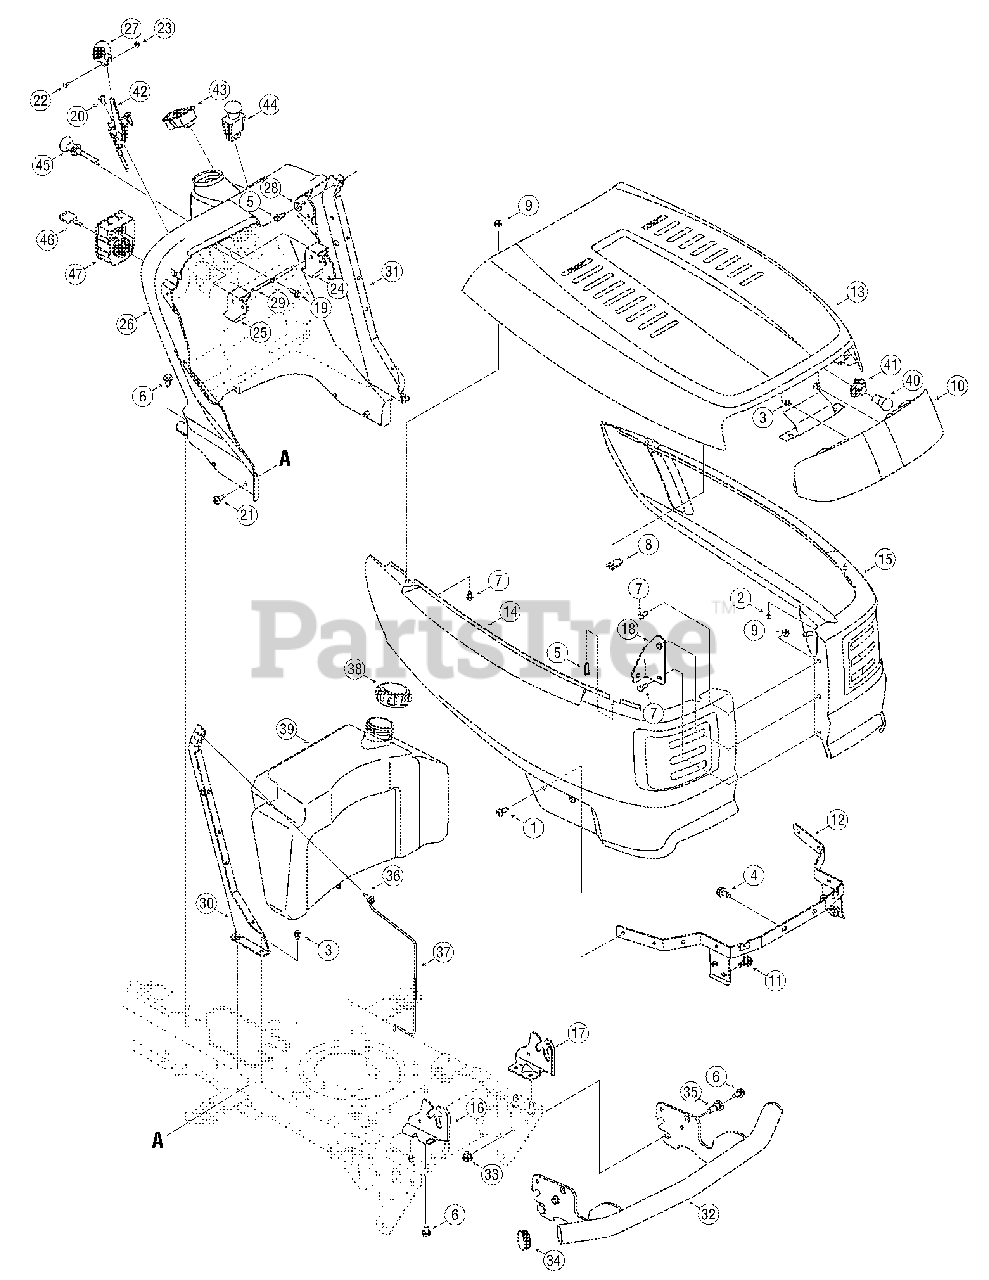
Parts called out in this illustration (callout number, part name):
1	Screw TT, 5/16-18 x.375
2	Screw #8-18 x.500
3	Screw TT, 1/4-20 x.500
4	Screw TT, 3/8-16 x.750
5	Screw TT, 1/4-20 x.750
6	Screw AB, 5/16-12 x.750
7	HH Cap Screw 1/4-20 x.620
8	Clip Nut 1/4-20
9	Flange Lock Nut 1/4-20
10	Lens
11	Shoulder Screw.43x.29:TT:5/16-18
20	Screw AB, 1/4-14 x.625
21	Screw TT, 5/16-18 x.750
22	Screw #8-32 x.375
23	Hex Nut #8-32
24	Brake Dash Lever
25	Cruise Dash Lever
26	Dash Panel
27	Control Knob
28	Bell Washer.265 x.75 x.062
29	Lever Rod
33	Flange Lock Nut 3/8-16
34	Bumper Cap
35	Shoulder Screw.498 x.340 x 3/8-16
36	Screw TT, 1/4-20 x.75
37	Tank Support Rod
38	Fuel Cap
39	Fuel Tank, 3 Gal.
40	Miniature Lamp, 12V
41	Socket, Lamp
42	Throttle Cable 39-inch
43	Systems Indicator Monitor w/Hour Meter
44	Electric PTO Switch
45	Choke Control 37.5" x 2
46	Ignition Key
46	Ignition Key w/ Plastic Cover
47	Ignition Switch Module
